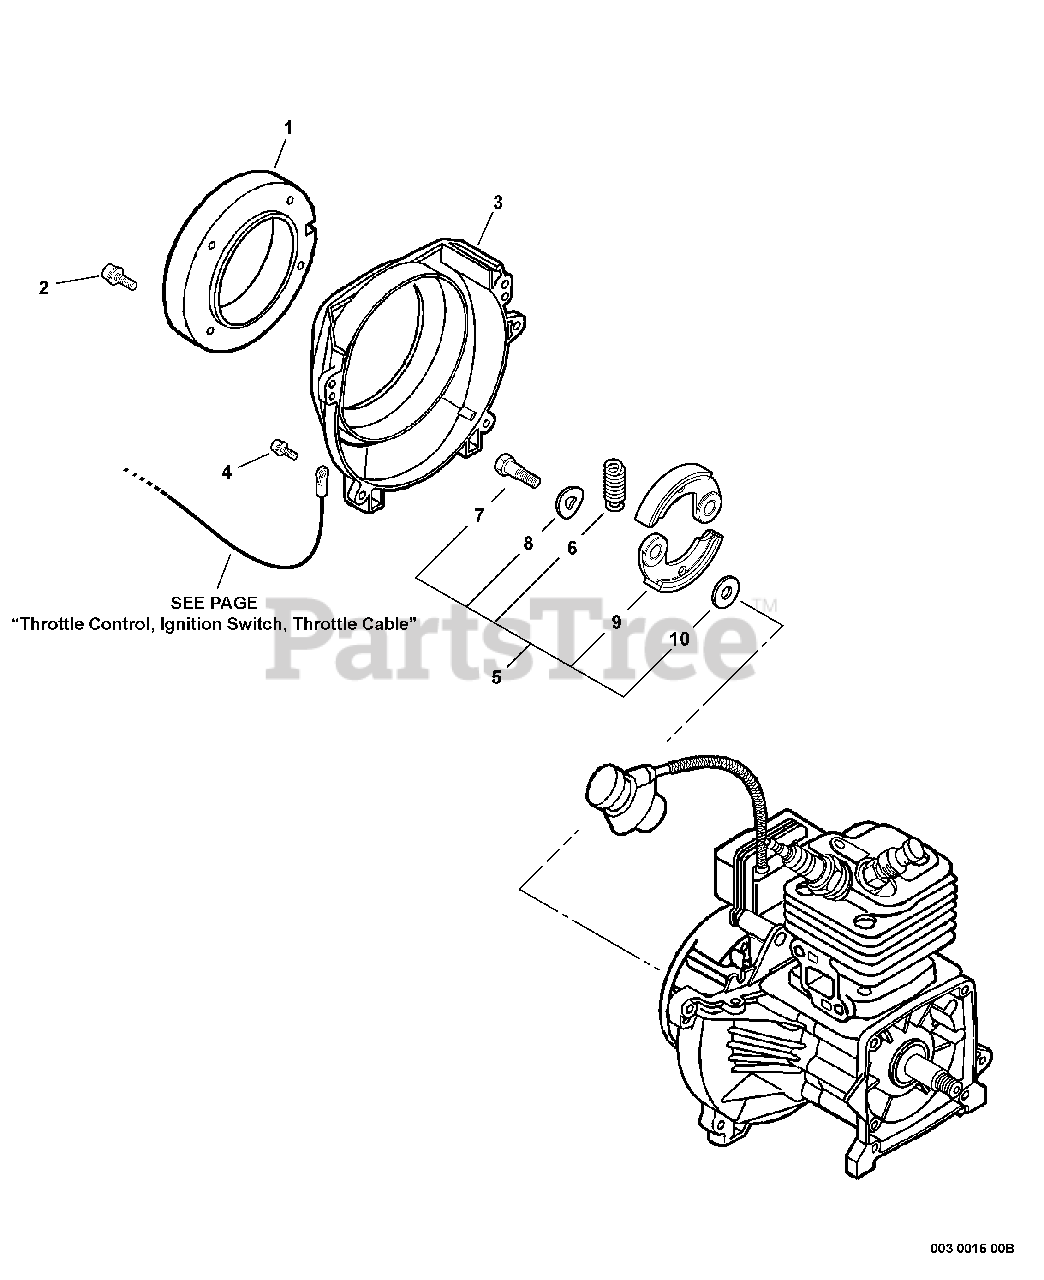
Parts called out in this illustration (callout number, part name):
1	PLATE, CLUTCH
2	BOLT 5×20
3	COVER, FAN
4	BOLT 5×20
5	CLUTCH ASSY
6	SPRING, TENSION
7	BOLT, CLUTCH
8	WASHER, WAVE
9	SHOE, CLUTCH
10	WASHER 8.2×17×1.6
